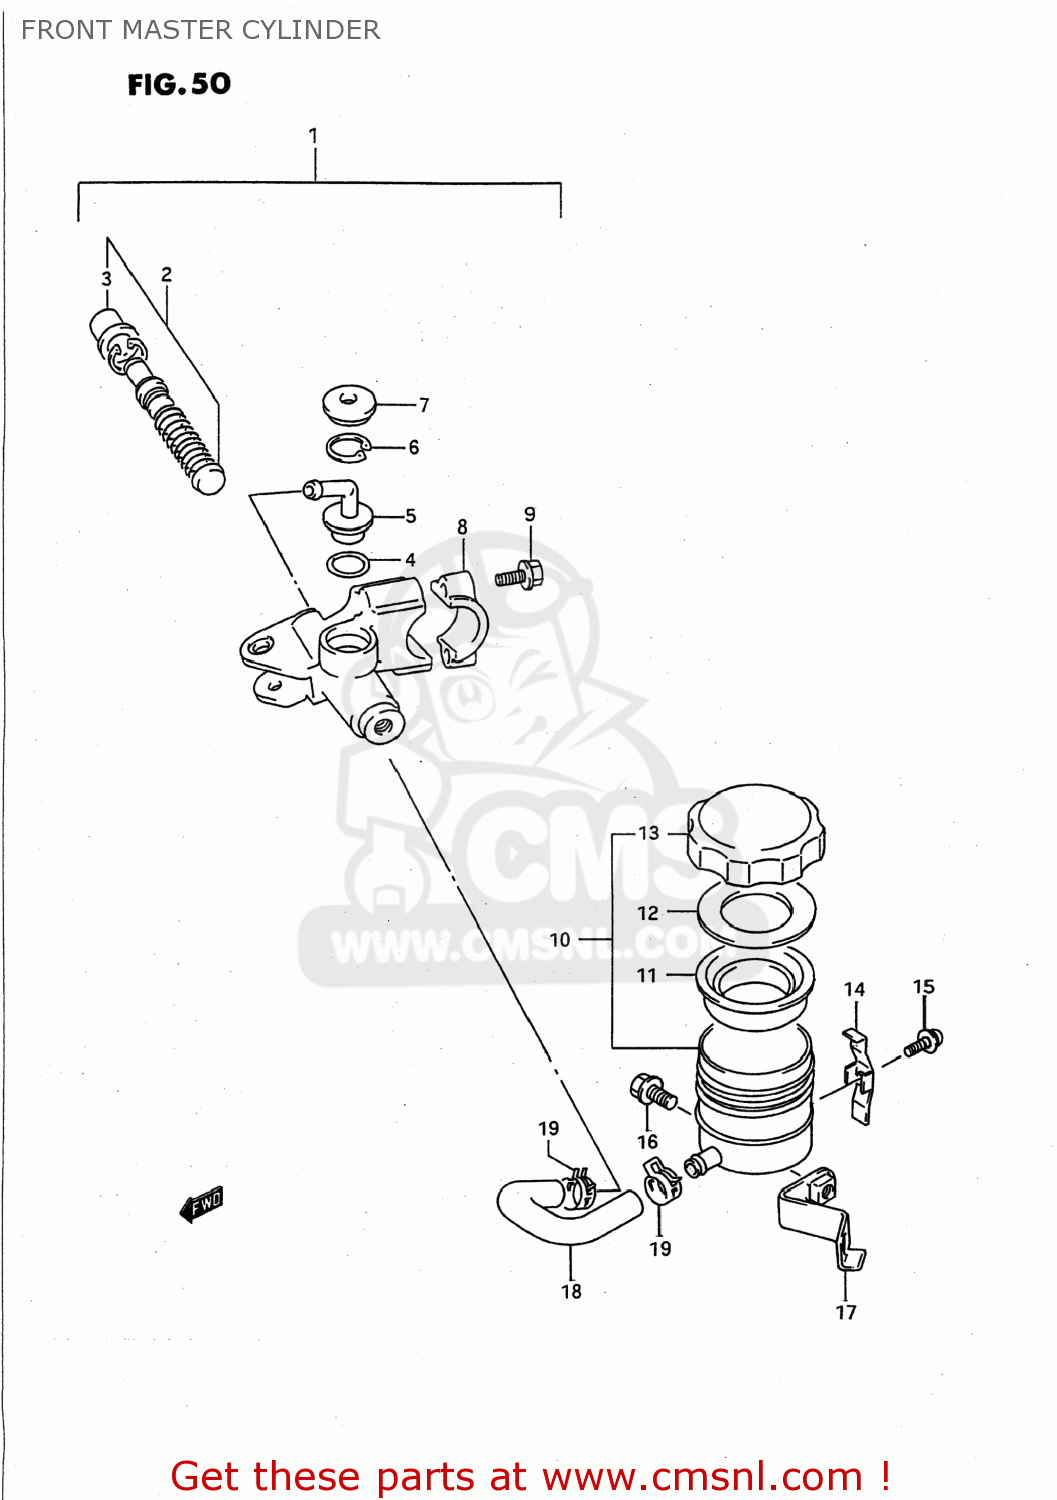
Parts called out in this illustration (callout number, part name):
1	CYLINDER ASSY,FR MASTER
2	PISTON & CUP SET
3	BOOT
4	O RING
5	CONNECTOR
6	CIRCLIP
7	COVER,DUST
8	HOLDER
9	BOLT(6X25)
10	TANK ASSY,RESERVOIR
11	DIAPHRAGM
12	PLATE,DIAPHRAGM
13	CAP
14	PLATE,RESERVOIR TANK CAP
15	SCREW
16	BOLT
17	BRACKET,RESERVOIR TANK
18	HOSE,RESERVOIR TANK FR
19	CLAMP,RESERVOIR TANK FR
20	TAG,RESERVOIR TANK BRACKET C
